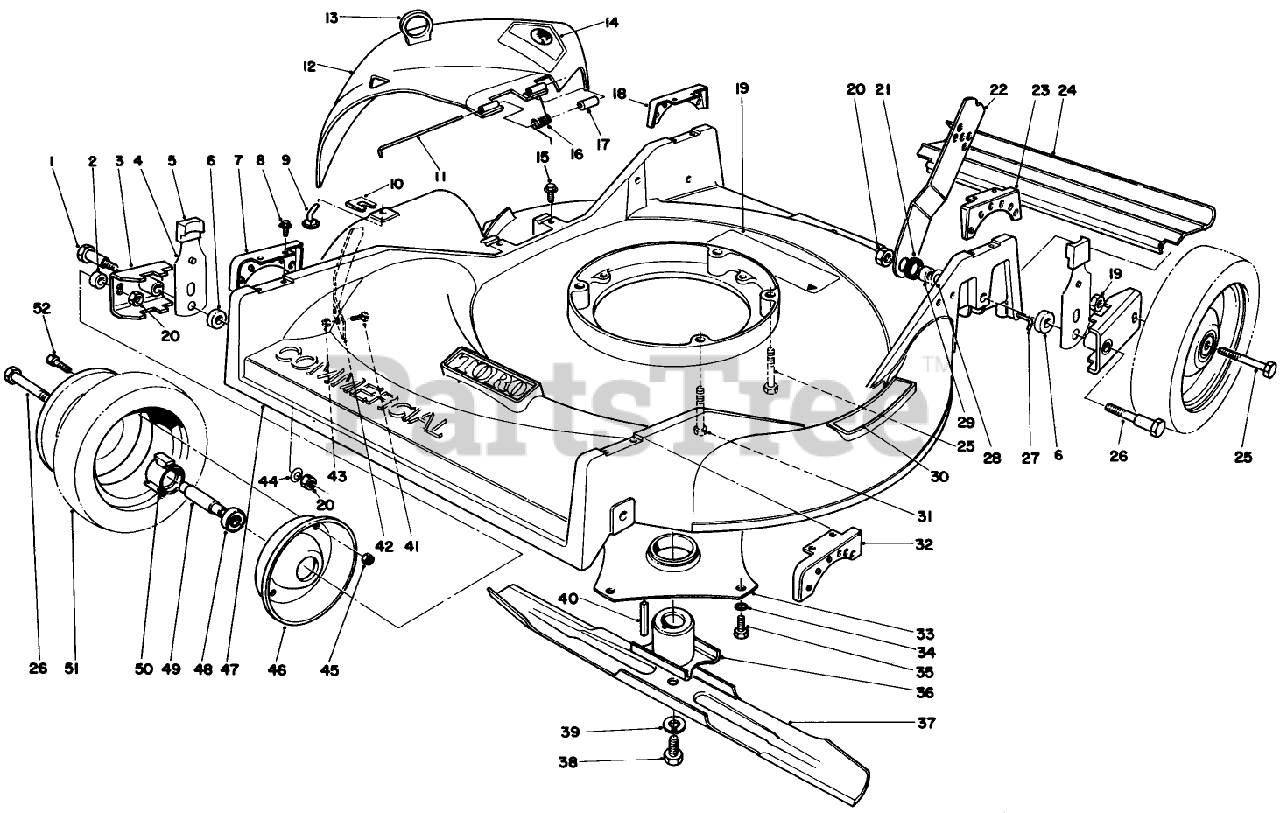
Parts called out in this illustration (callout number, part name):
1	PIVOT SCREW
2	SPACER-WHEEL
3	PIVOT ARM
4	SPRING ARM ASM-FRONT
5	KNOB-ARM
6	SPACER-PIVOT
7	FRT RIGHT QUAD
8	SCREW-HWHTF
9	BAG CHUTE PIN
10	BAG CHUTE CLIP PIN
12	DEFLECTOR
13	LIFT LOOP
14	DECAL-DANGER
15	SCREW-HWH
16	DEFLECTOR SPRING
20	NUT-LOCK, NI
21	HANDLE LATCH SPACER
25	SCREW-HH
26	REAR PIVOT SCREW
27	SHIELD ROD
28	WASHER-BELLEVILLE
29	HANDLE LATCH SPACER
30	STEP PAD DECAL
31	SCREW-HH
33	CRNKSHFT PROTECT ASM
34	WASHER-LOCK, INTERNAL
35	SCREW-HWHTF
38	SCREW-HH
39	WASHER-LOCK
40	KEY-SQUARE
41	SCREW-CARR
43	NUT-LOCK, NI
44	WASHER-BELLEVILLE
45	NUT-LOCK, NI
48	BEARING-WHEEL
49	SPACER-BEARING
50	HUB-BEARING
52	SCREW-HHF
